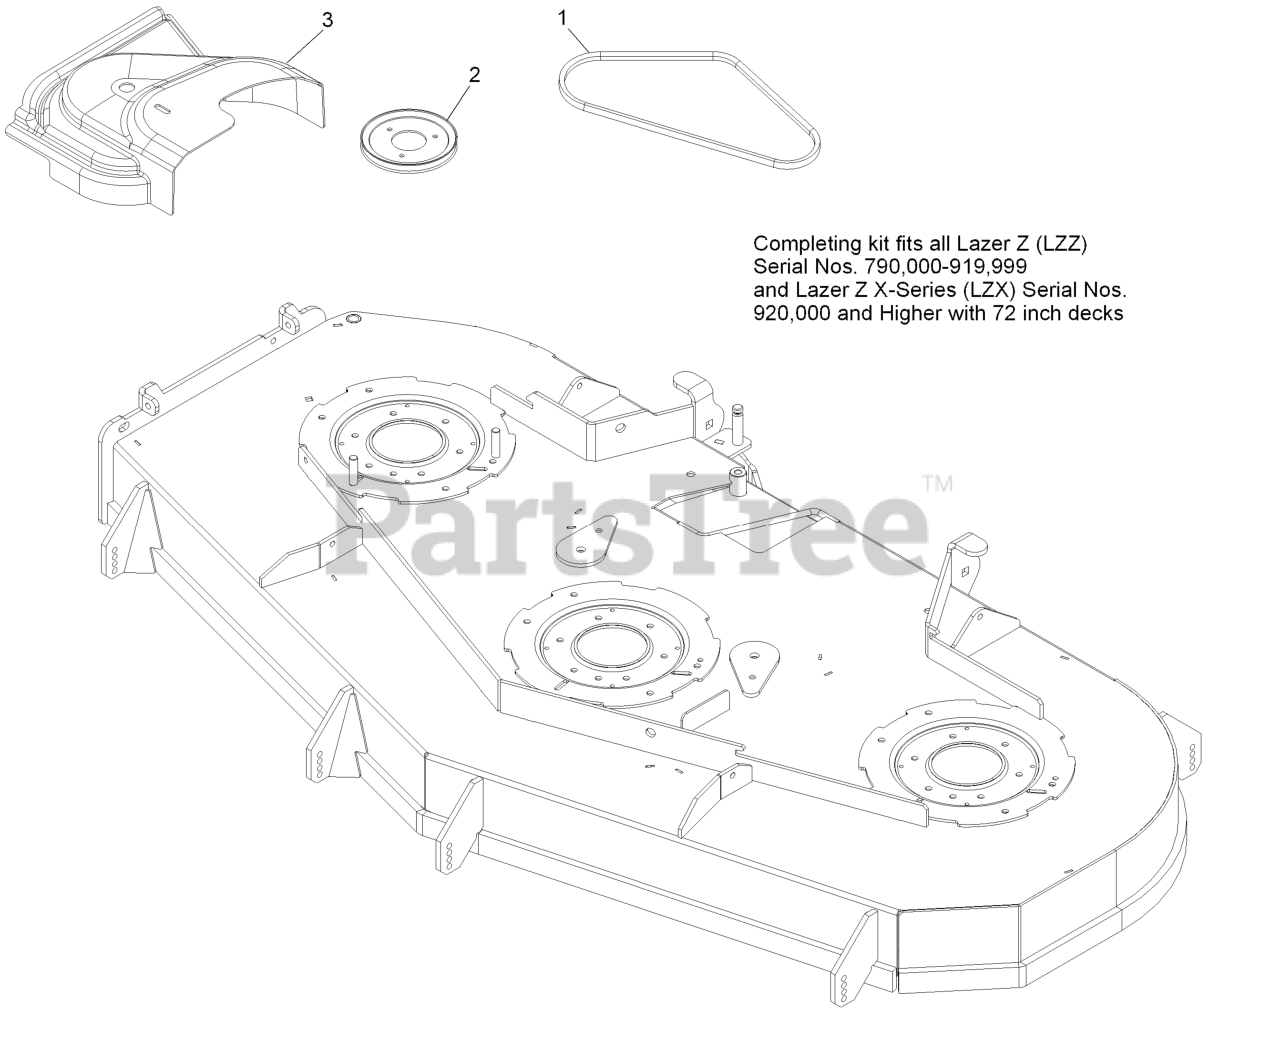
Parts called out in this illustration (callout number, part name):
1	Belt, Blower Drive 72
2	Sheave,Drive Lzuv 726
3	Cover,Belt Uv 72
